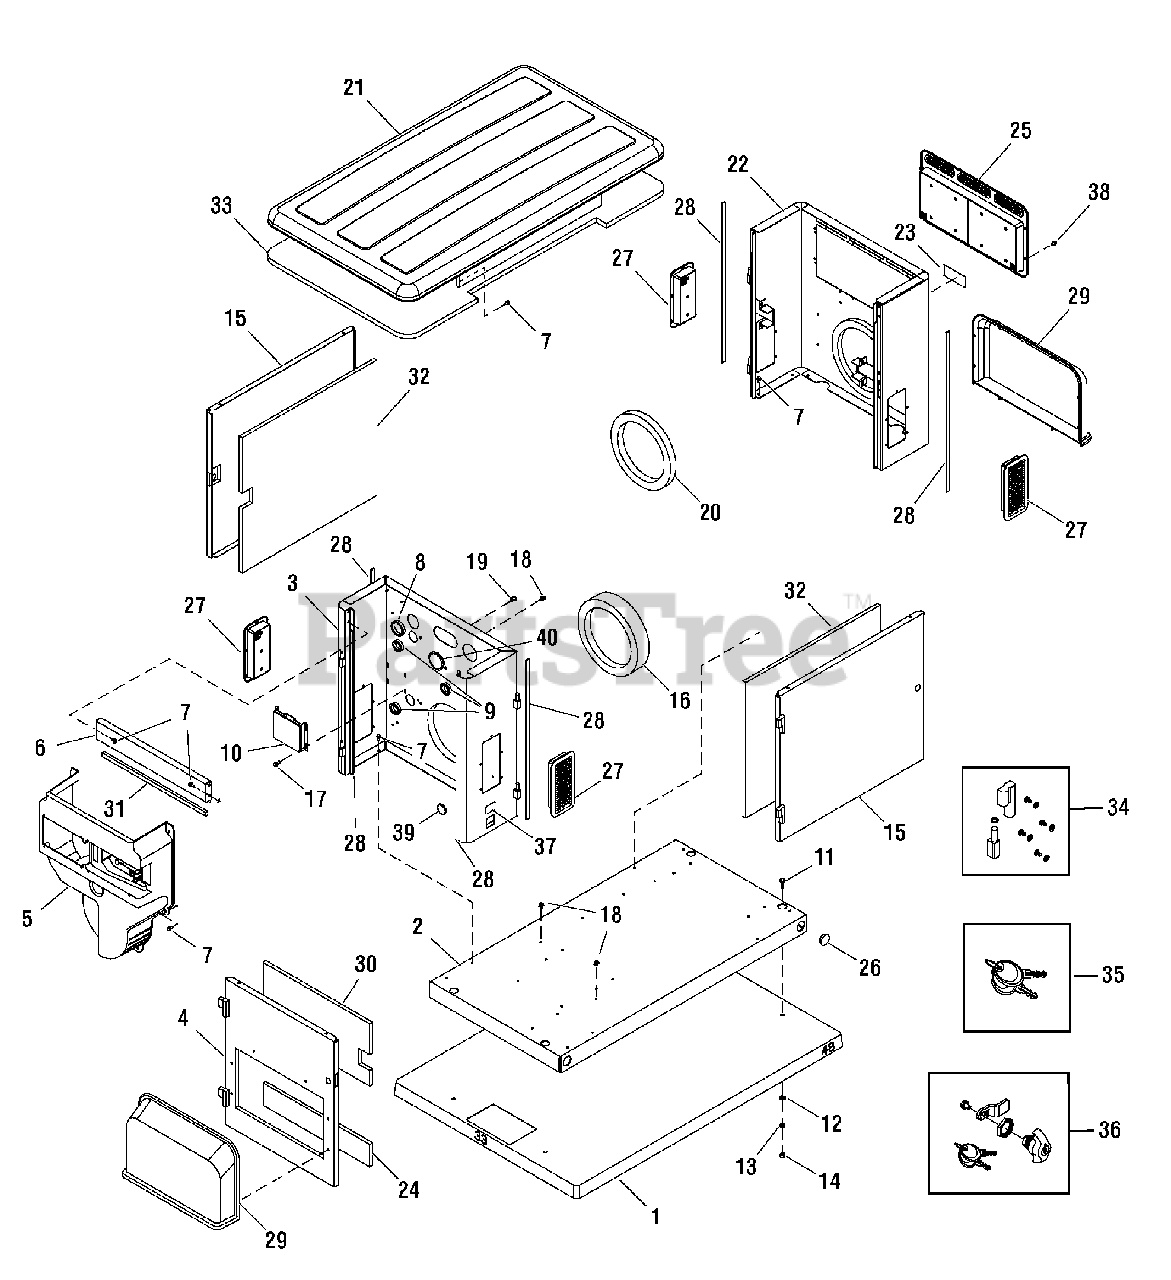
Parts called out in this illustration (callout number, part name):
2	BASE
3	BULKHEAD, Engine
7	BOLT
10	REGULATOR, Voltage
11	* CAPSCRREW, Hex Head, 3/8-16 x 1
12	* WASHER, Flat,3/8-M10
13	* WASHER, Lock, 3/8
14	* NUT, 3/8-16
16	SEAL, Foam
20	SEAL, Foam
22	BULKHEAD, Alternator
29	COVER, Air Intake
37	DECAL
